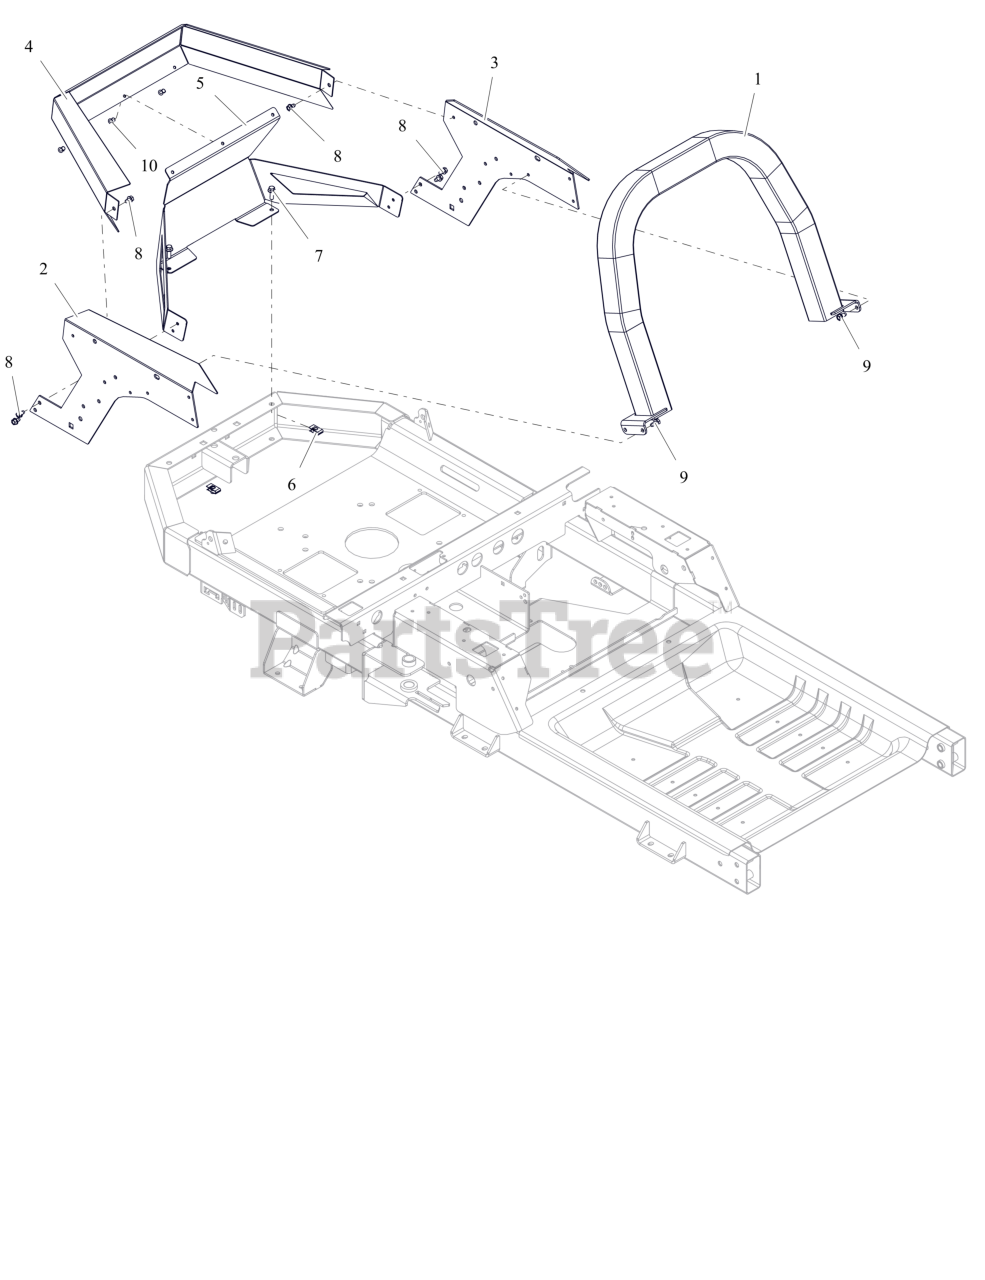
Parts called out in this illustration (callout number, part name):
1	GUARD- ENGINE TRIM
2	PANEL, RIGHT REAR FENDER MOUNT (ORANGE)
3	PANEL, LH REAR FENDER MOUNT (ORANGE)
4	GUARD, ENGINE WRAP (ORANGE)
5	GUARD- ENGINE
6	NUT-RTNR .25-20X.56
7	BLT,HEX-FLG .25-20X.75 G5 BFP
8	SCR,TAP .25-20X.375 HWH TR ZCC
9	SCR-TAP .25-20X.50 HWH ZCC
10	RIVET, #66 STEEL POP PD BLACK
